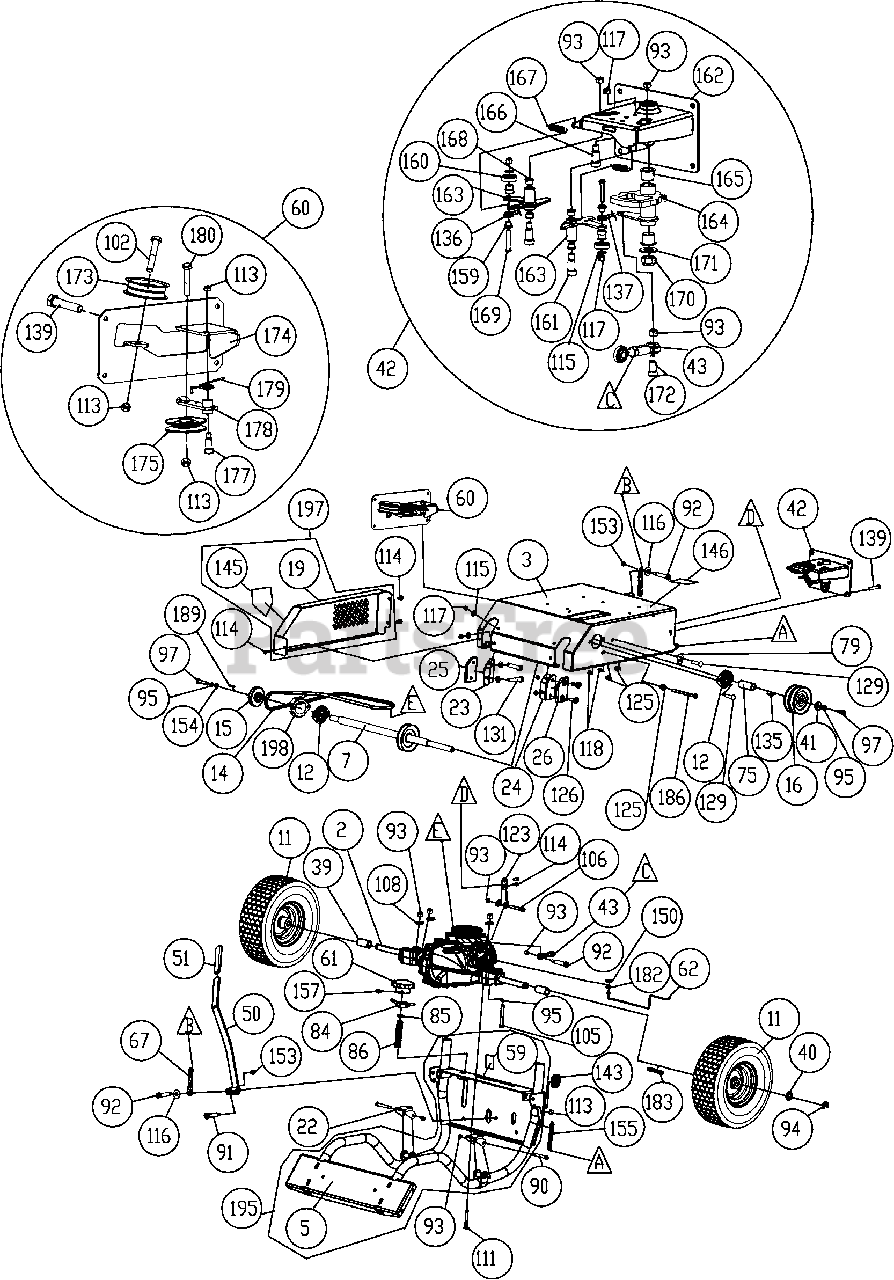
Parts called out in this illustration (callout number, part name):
2	TRANSAXLE
3	ENGINE BASE WA
5	FRAME SUPPORT OS900SP WA
7	JACKSHAFT WA
11	REAR WHEEL13" X 5" PNEU ASSY
12	BEARING & FLANGETTE ASSY
14	BELT 3L540
15	PULLEY 0.75" ID X 2.75
16	PULLEY 0.75" ID X 4" 4L SECTION
19	GUARD DRIVE BELT OS900SP
22	BRACKET FIXED FRONT FRAME
23	BRACKET RH WEAR PAD OS900SP
24	BRACKET LH WEAR PAD OS900SP
25	WEAR PAD RH OS900SP
26	WEAR PAD LH OS900SP
39	SPACER REAR WHEEL OS900SP
40	WASHER .765 ID X 1.25 OD X .06 THK
41	WASHER 1.125 OD X .344 ID X 10 GA
42	SPEED CONTROL ASSY
43	CONNECTOR SPEED CONTROL
50	LEVER HEIGHT CONTROL WA
51	GRIP LEVER LIFT
59	LABEL DEPTH GAUGE OS900SP
60	MULE ASSY
61	KNOB HAND
62	ROD BYPASS ARM TRANSAXLE
67	LINK, LIFT ARM WA OS900SP
75	SPACER PULLEY JACKSHAFT
79	BRACKET CLUTCH CABLE
84	LOCKNUT WA
85	WASHER .75"
86	STUD 3/4"-10 X 3 3/4 PLTD
90	BOLT SHOULDER 3/8" X 2"
91	BOLT SHOULDER 1/2" X 2"
92	BOLT SHOULDER 3/8" X 1/2"
93	NUT LOCK 5/16"-18
94	RING RETAINING EXTERNAL 3/4"
95	WASHER SPLIT LOCK
97	SCREWCAP 5/16-24 X 1"
102	SCREWCAP 3/8"-16 X 1 3/4" HCS ZP
105	SCREWCAP 5/16"-18 X 3" HCS ZP
106	SCREWCAP 5/16"-18 X 2"
108	WASHER 5/16 FLAT
111	BOLT CARRIAGE
113	LOCK NUT 3/8-16
114	SCREW SELF TAP 1/4"-20 X 5/8" HWH TYPE F
115	WASHER 1/4" SAE
116	WASHER 3/8" SAE
117	LOCK NUT 1/4-20
118	NUT 5/16"-18 SER. HEX WSHR FLNG ZP
123	BRACKET TORQUE LIMITING
125	NUT 5/16"-18 SER HEX WASHER FLNG ZP
126	SCREW SPOT WELD 5/16"-18 X 3/4 W/PROJ
129	BOLT CARRIAGE 5/16"-18 X 3/4" ZP
131	SCREWCAP 1/4"-20 X 1" HCS ZP
135	KEY 3/16" SQ X 1 1/4"
136	CABLE SPEED CONTROL RT
137	CABLE SPEED CONTROL LFT
139	SCREWCAP 5/16" SER HEX WSHR FLNG GR. 5 ZP
143	GROMMET 1.25" HOLE
145	LABEL WARNING OPEI
146	LABEL DRIVE RELEASE OS900SP
150	PIN CLIP HITCH 0.051 X 3/4"
153	NUT LOCK 5/16"-18 LT WT TH ZP
154	WASHER FENDER 5/16"
155	SPRING LIFT ASSIST OS900SP
157	SCREW MACH #10-24 X 2" HWF ZP
159	SPACER EYELET SPEED CONTROL OS900SP
160	BEARING 1/2" ID X 1.125 OD
161	BOLT SHOULDER 3/8" X 1 3/4"
162	BRACKET SPEED CONTROL WA OS900SP
163	BELLCRANK SPEED CONTROL WA OS900SP
164	CAM SPEED CONTROL WA
165	BUSHING PIVOT FRAME AE
166	BOLT SHOULDER 5/16" X 1 1/2"
167	SPRING EXTENSION
168	BUSHING 3/8" ID X 1/2" OD X 3/8"
169	SCREWCAP 1/4-20 X 1 3/4 SKT BUT HD
170	NUT LOCK 5/8"-11 LT WT TH ZP
171	WASHER 5/8" SAE
172	SCREWCAP 5/16"-18 X 1" HCS ZP
173	PULLEY IDLER 2.75" OD X 3/8" BORE
174	BRACKET DRIVE BELT WA OS900SP
175	PULLEY 3V GROOVE IDLER
177	BOLT SHOULDER 1/2" X 2"
178	ARM IDLER MULE DRIVE WA OS900SP
179	SPRING IDLER MULE DRIVE OS900SP
180	SCREWCAP 3/8"-16 X 1 1/2" HCS ZP
182	WASHER #10 SAE
183	KEY 3/16" SQ X 2 1/8"
186	SCREWCAP 5/16"-18 X 5" HCS ZP
189	KEY 3/16" SQ X 5/8"
195	FRAME SUPPORT OS900SP WA W/LABELS
197	DRIVE BELT GUARD WA W/LABELS
198	BRACKET BELT GUIDE OSSP
